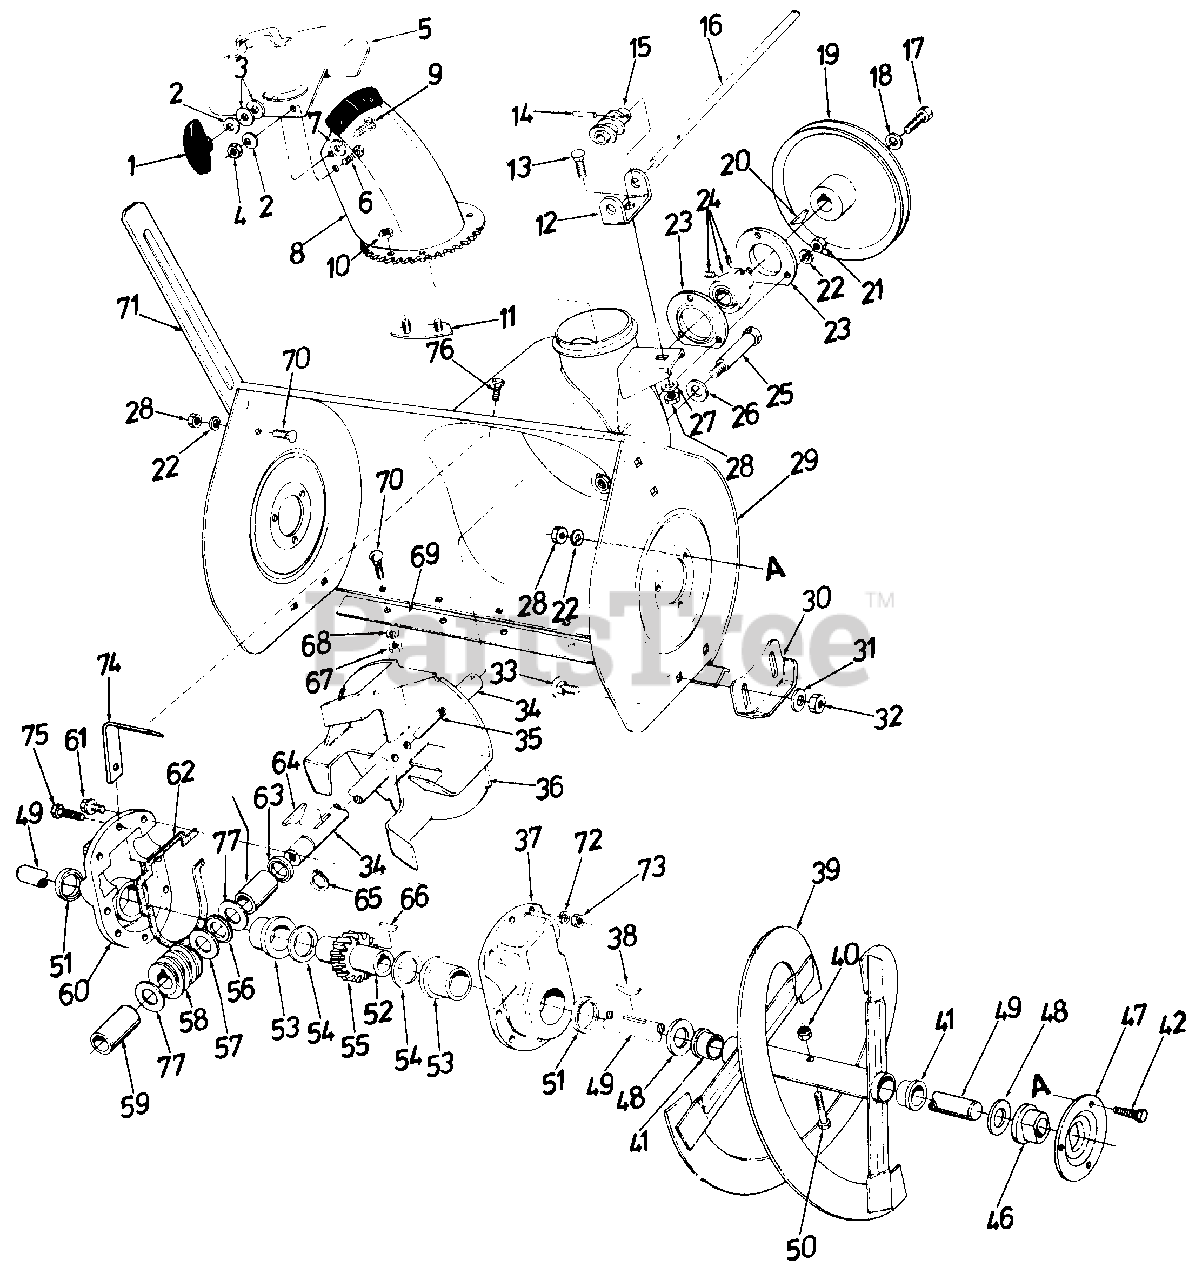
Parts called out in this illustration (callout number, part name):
1	Hand Knob Ass'y.
2	Bell-Wash. .345 I.D. x .88 O.D. x .060
3	Fl-Wash. .312 I.D. x 1.125 O.D. x .125
4	Hex Cent. L-Nut 5/16-18 Thd.
5	Top Chute Ass'y.
6	Carr. Bolt 5/16-18 x .62" Lg.
7	Fl-Wash. .53 I.D. x 1.25 O.D. x .100
8	Chute Ass'y.
9	Carr. Bolt 5/16-18 x 1.00" Lg.
10	Hex Cent. L-Nut 1/2-20 Thd.
11	Chute Flange Keeper Ass'y.
12	Chute Brkt.
13	Carr. Bolt 5/16-18 x .62" Lg.
14	Spring Pin Roll 1/8" Dia. x .75" Lg.
15	Worm - R.H. w/Three Threads
16	Chute Crank .38" Dia. x 41.0" Lg.
17	Hex L-Scr. 5/16-18 x .88" Lg.
18	Bell-Wash. .345 I.D. x .88 O.D. x .060
19	V-Pulley .875 I.D. x 10.12 O.D.
20	#9 Hi-Pro Key 3/16 x 3/4" Dia.
21	Hex Nut 5/16-18 Thd.
22	L-Wash. 5/16" Scr.
23	Bearing Hsg. - Self Aligning Brg.
24	Self Aligning Brg. .875 I.D.
25	Stud 3/8-16 x 2.75" Lg.
26	Bell-Wash. .400 I.D. x .88 O.D. x .060
27	Bell-Wash. .345 I.D. x .88 O.D. x .060
28	Hex Nut 5/16-18 Thd.
29	Blower Hsg. Ass'y.
30	Slide Shoe
31	Bell-Wash. .400 I.D. x .88 O.D. x .060
32	Hex Nut 3/8-16 Thd.
33	Carr. Bolt 3/8-16 x .75" Lg.
34	Blower Axle
35	Spring Pin Spiral 5/16" Dia. x 1.75" Lg.
38	#91 Woodruff Key 1/4" x 3/4" Dia.
41	Plastic Bushing
42	Hex Sems Scr. 5/16-18 x .75" Lg.
46	Flange Brg. w/Flats 1.00" I.D.
47	Bearing Hsg. - Spiral Hsg.
48	Fl-Wash. 1.06 I.D. x 1.75" O.D. x .100
49	Spiral Axle - 26"
50	Hex Scr. 5/16-18 x 1.75" Lg.
51	Oil Seal 1.50" I.D.
52	Worm Gear Shaft
53	Flange Brg. 1.503 I.D.
54	Fl-Wash. 1.50 I.D. x 2.00 O.D. x .030
55	Double Threaded Worm Gear
56	Thrust Brg. .88 I.D. x 1.44 O.D. x .078
57	Fl-Wash. .88 I.D. x 1.40 O.D. x .150
58	Double Threaded Worm - L.H.
59	Sleeve Brg. .875 I.D.
60	Complete Gear Hsg. Half - R.H.
61	Hex Scr. 5/16-18 x 1.00" Lg.
62	Gasket
63	Oil Seal .875" I.D.
64	#9 Hi-Pro Key 3/16 x 3/4" Dia.
65	Snap Ring for .875" Dia. Shaft
66	#91 Woodruff Key 1/4 x 3/4" Dia.
67	Hex Nut 5/16-18 Thd.
68	L-Wash. 5/16" Scr.
70	Carr. Bolt 5/16-18 x .62" Lg.
71	Drift Cutter
72	Wave Wash. 5/16" Scr.
73	Hex Ins. L-Nut 5/16-18 Thd.
74	Gear Hsg. Support Brkt.
75	Hex Scr. 5/16-18 x 1.25" Lg.
76	Hex Wash. Hd. Self-Tap Scr. 5/16-24 x .50" Lg.
77	Fl-Wash. .88 I.D. x 1.40 O.D. x .150
